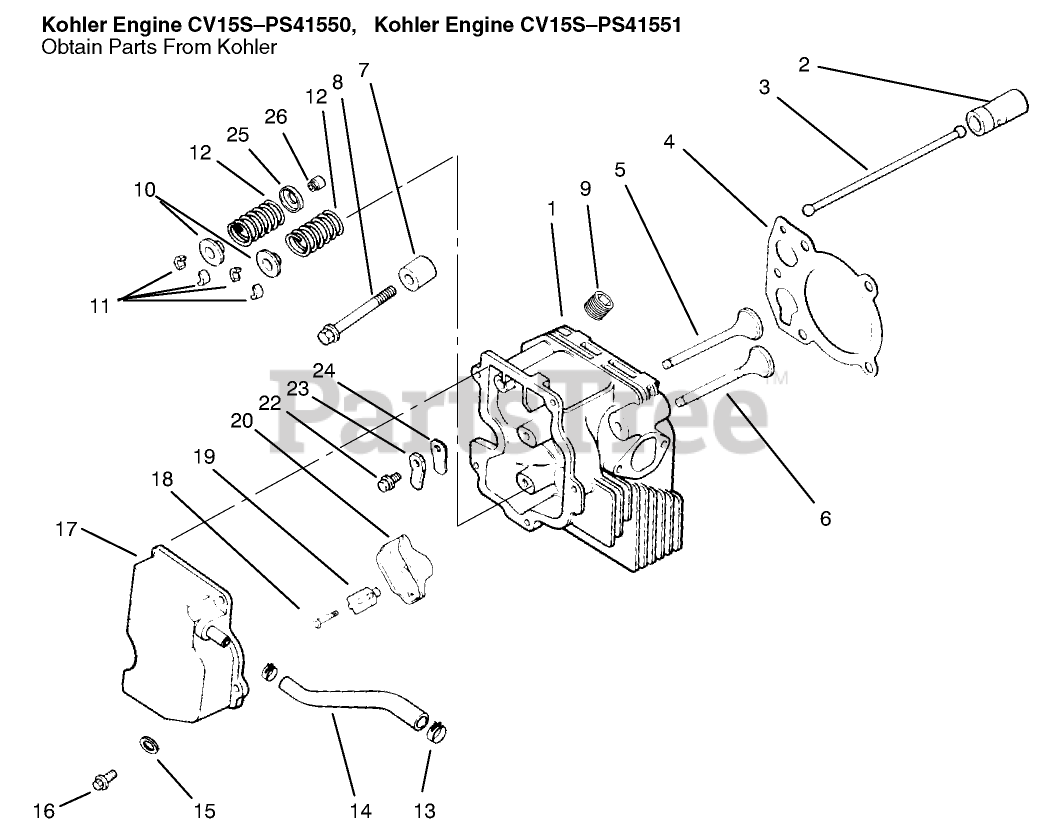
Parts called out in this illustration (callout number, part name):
1	Cylinder Head
2	Lifter-Valve
3	Rod-Push (Only On: 72042,72043,72062,72063)
4	Gasket-Cylinder Head
5	Valve-Intake STD (Only On: 72042, 72063, 72062, 72043)
5	Valve-Intake .25 (Only On: 72042,72043,72062,72063)
6	Valve-Exhaust STD (Only On: 72042,72043,72062,72063)
6	Valve-Exhaust .25 (Only On: 72042, 72063, 72062, 72043)
7	Spacer-Head Bolt Exhaust (Only On: 72042, 72063, 72062, 72043)
8	Screw M10x1.5x80 (Only On: 72042, 72063, 72062, 72043)
10	Cap-Valve Spring
11	Kit-Retainer
12	Spring-Valve Intake (Only On: 72042, 72063, 72062, 72043)
13	Clamp
14	Hose-Breather (Only On: 72042, 72063, 72062, 72043)
15	Washer-Flat (Only On: 72042, 72063, 72062, 72043)
17	Cover-Valve W/Nipple (Only On: 72042, 72063, 72062, 72043)
19	Pivot-Rocker Arm
20	Arm-Rocker
23	Retainer-Reed
24	Reed-Breather
25	Retainer-Spring
26	Seal-Valve Stem
